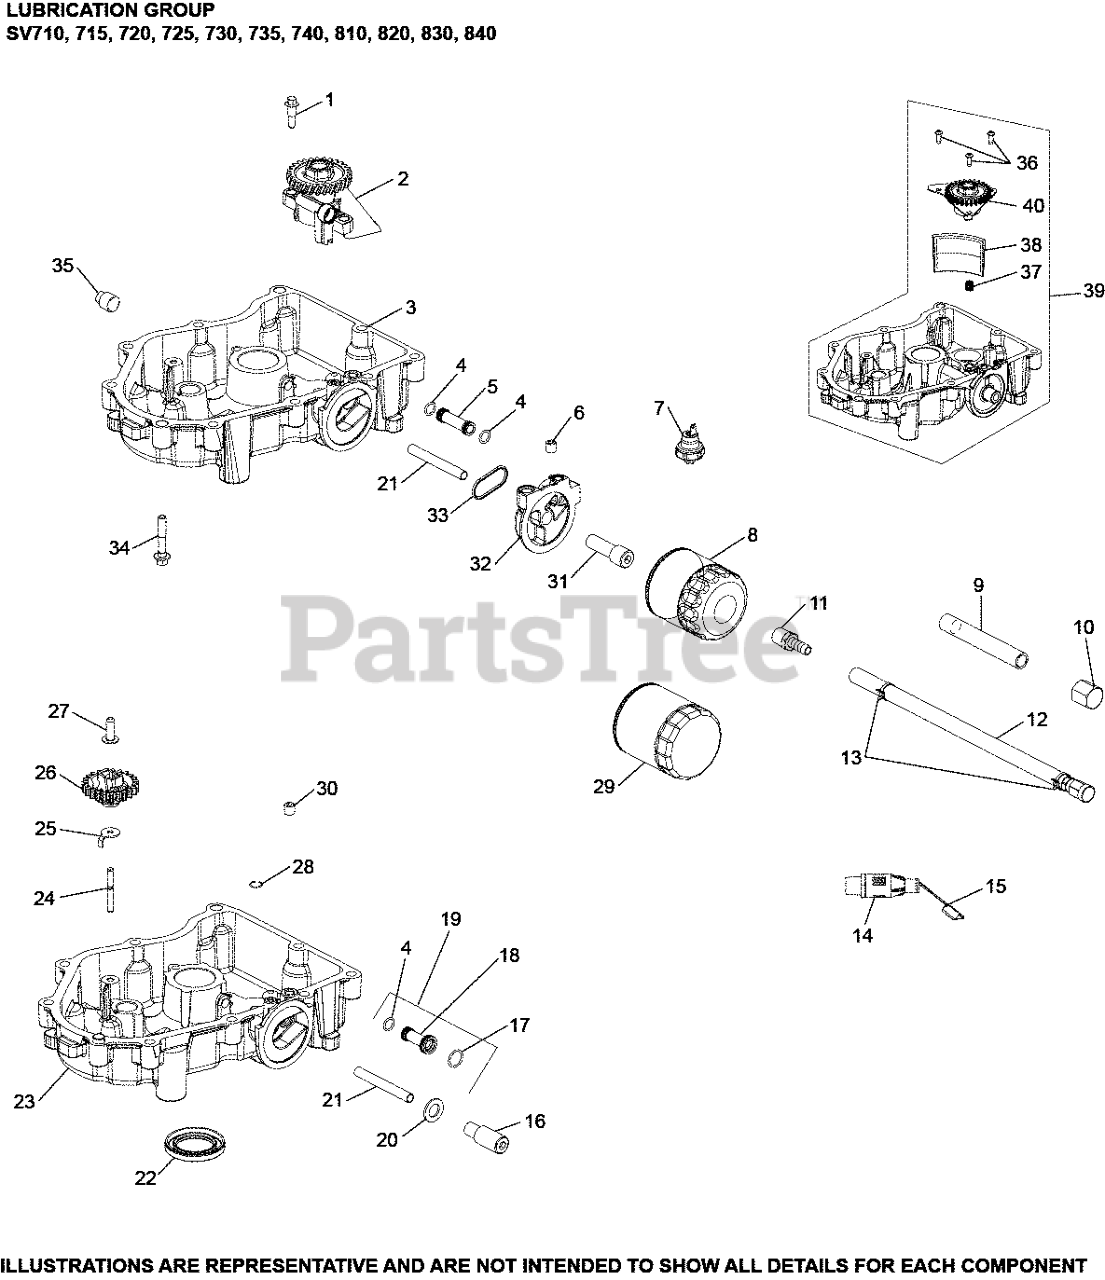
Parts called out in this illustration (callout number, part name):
1	SCREW, SHD THD FRM M6X.0X6.5
2	PUMP ASSEMBLY, OIL - DISCONTINUED
3	OIL PAN ASSEMBLY-USE 32 199 14-S
4	O-RING, OIL PICK-UP
5	TUBE, OIL FEED
6	PLUG, CTSK PIPE 1/8"
21	TUBE, OIL FEED - FILTER TO PAN
22	SEAL, OIL (KM)-USE 25 032 06-S
24	SHAFT, GOVERNOR GEAR
25	TAB, LOCKING
26	KIT, GOVERNOR GEAR W/PIN
27	PIN, GOVERNOR REGULATING
29	OIL FILTER
31	NIPPLE, OIL FILTER
32	ADAPTER, OIL FILTER -USE 32 029 10-S
33	O-RING, OIL FILTER ADAPTER
34	SCREW, FLG M8X1.25X45
35	PLUG, SQ HD PIPE 3/8"
